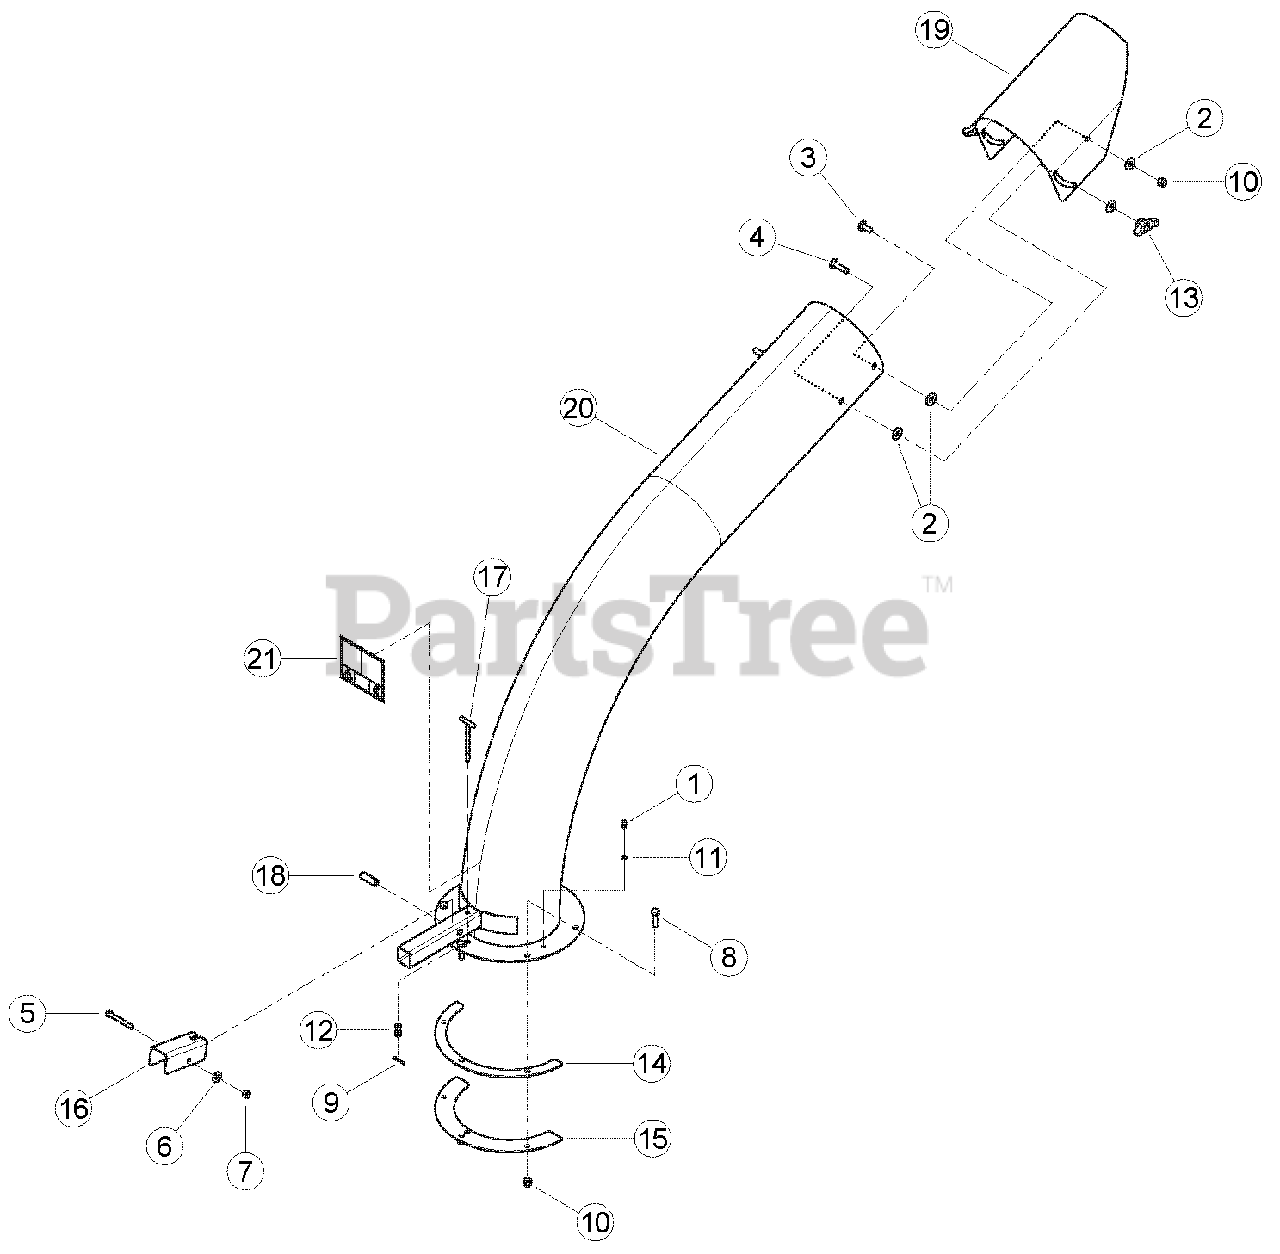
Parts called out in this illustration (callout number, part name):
1	FITTING, 1/4 SELF-TAP GREASE
2	WASHER, 3/8 FLAT ZP
3	BOLT, 3/8 X 1 CRG GR5 NC ZP
4	BOLT, 3/8 X 1-1/2 CRG GR5 NC ZP
5	BOLT, 5/16 X 2-1/2 HX CAP GR5 ZP
6	WASHER, 5/16 FLAT ZP
7	NUT, 5/16 NE NYLOCK ZP
8	BOLT, 3/8 X 1-1/4 HEX HD GR5 ZP
9	PIN, 1/8 X 1 ZP COTTER
10	NUT, 3/8 NE NYLOCK ZP
11	WASHER, .254 X .400 X .048 FLAT
12	SPRING, LOCK COMPRESSION
13	KNOB, 3/8-16 UNC FEMALE TEE
14	RING, DISCHARGE SPACER
15	RING, DISCHARGE CLAMP
16	LEVER, DISCHARGE LOCK
17	WELDMENT, DISCHARGE LOCK PIN
18	TUBE, DISCHARGE LOCK PIVOT
19	CAP, 8 IN. DISCHARGE CHUTE
20	ASSEMBLY, 8 INCH DISCHARGE, SERVICE PART
21	DECAL, DISCHARGE DEBRIS & LOCK
